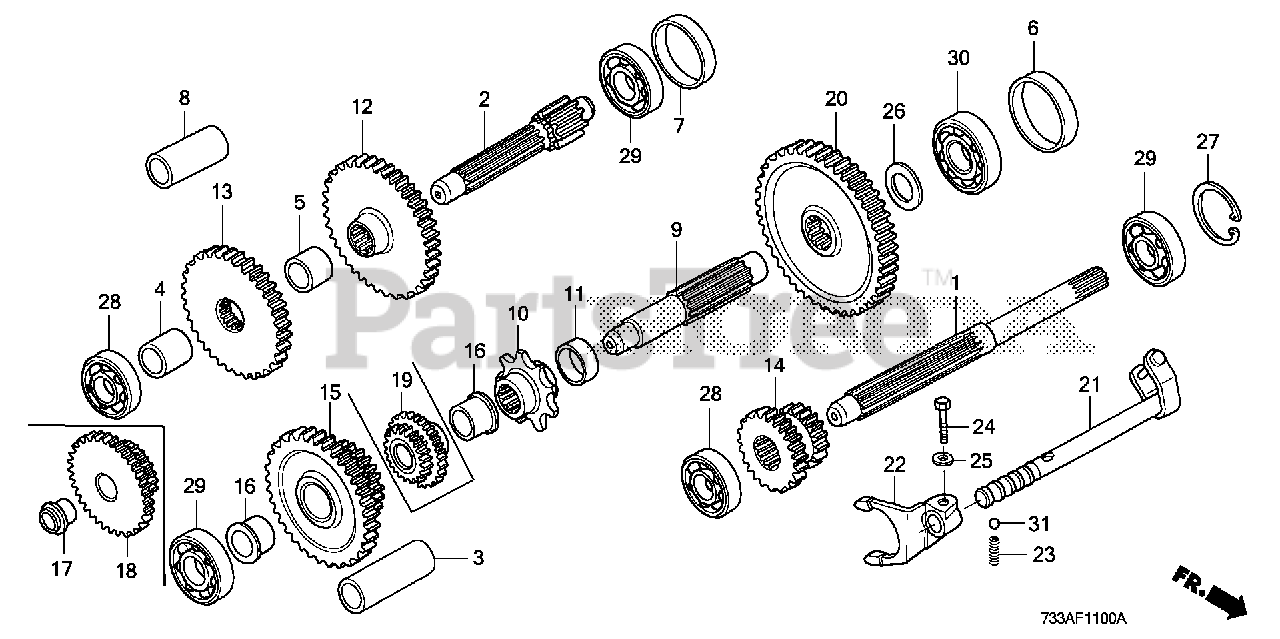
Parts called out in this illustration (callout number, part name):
1	SHAFT, INPUT
2	COUNTERSHAFT (13T)
4	COLLAR A, COUNTERSHAFT
5	COLLAR B, COUNTERSHAFT
6	COLLAR A, DISTANCE
7	COLLAR B, DISTANCE
9	SHAFT, FINAL
10	SPROCKET, DRIVE (9T)
11	COLLAR, FINAL SHAFT
12	GEAR, COUNTERSHAFT FIRST (50T)
13	GEAR, COUNTERSHAFT SECOND (45T)
14	GEAR, CHANGE (18T/23T)
15	GEAR, REVERSE IDLE (49T-25T)
16	COLLAR, IDLE GEAR
20	GEAR, FINAL (58T)
21	SHAFT, SHIFT FORK
22	FORK, SHIFT
23	SPRING, BALL SETTING
24	BOLT, SPECIAL
25	WASHER, CONICAL SPRING
26	WASHER (17MM)
27	CIRCLIP, INNER (35MM)
28	BEARING, RADIAL BALL (6002)
29	BEARING, RADIAL BALL (6202)
30	BEARING, RADIAL BALL (6203)
31	BALL, STEEL (#8) (1/4)
